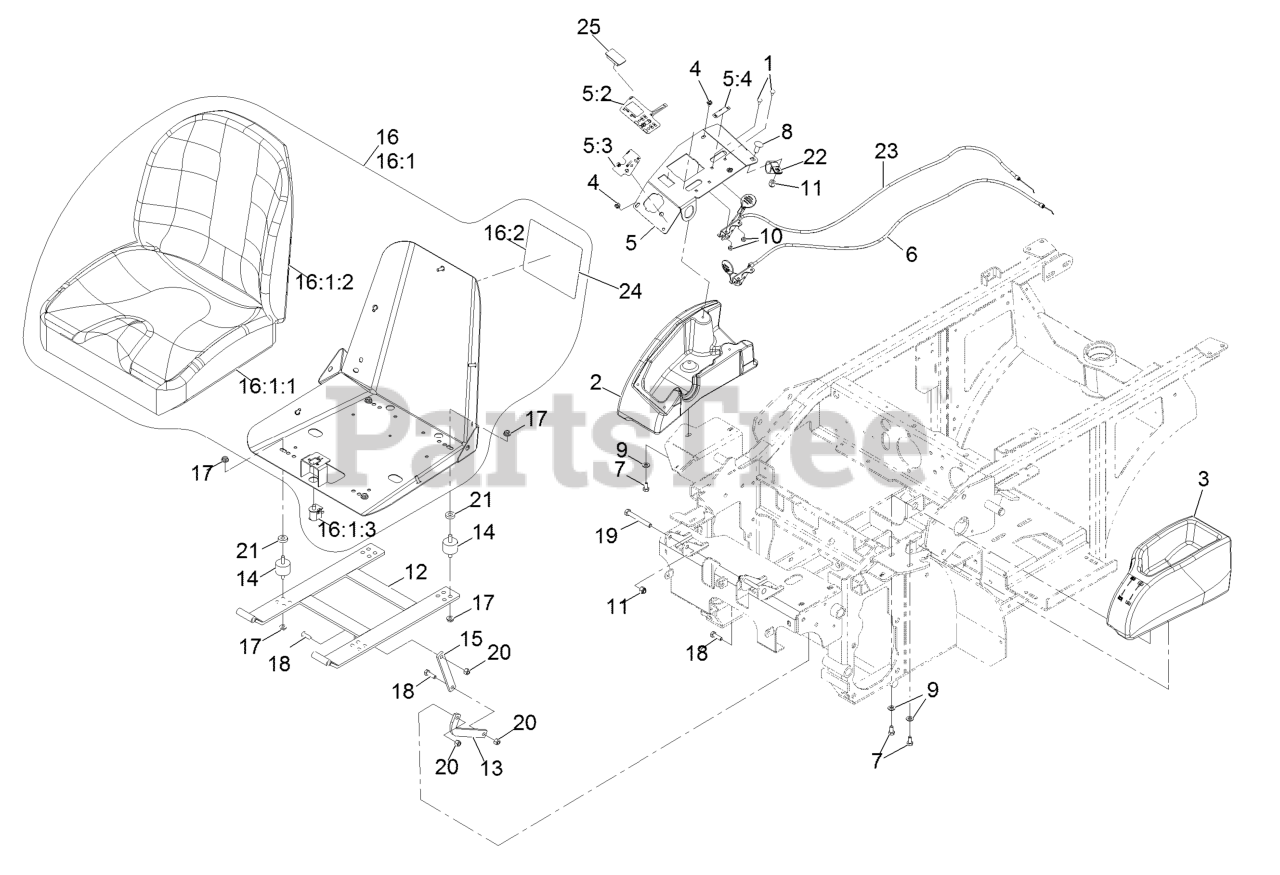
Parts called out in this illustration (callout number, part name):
1	BOLT-CARR
2	CONSOLE-RH
3	CONSOLE, LH GREY
4	SCREW-PPH
5	CONTROL PANEL ASM
5:2	Decal-Nav Console 640Kc
5:3	DECAL-SPEED CONTROL
5:4	DECAL-CHOKE
6	CABLE-THROTTLE
7	SCREW-HH
8	SCREW-CARR
9	WASHER-PLAIN
10	NUT-LOCK, NI
11	NUT-LOCK, NI
12	FRAME-SEAT
13	LINK-SEAT STOP
14	MOUNT-VIBRATION, RUBBER
15	LINK-SEAT
16:1	Seat ASM
16:1:1	ASM-SEAT BOTTOM CUSHION
16:1:2	CUSHION,SEAT BACK
16:1:3	SWITCH-BAIL
16:2	Decal-Service Aid
18	SCREW-HH
19	SCREW-CARR
20	NUT-LOCK, NI
21	SPACER
22	CLIP-LOOM
23	CABLE-CHOKE
24	Decal-Service Aid
25	PLUG-HOLE
